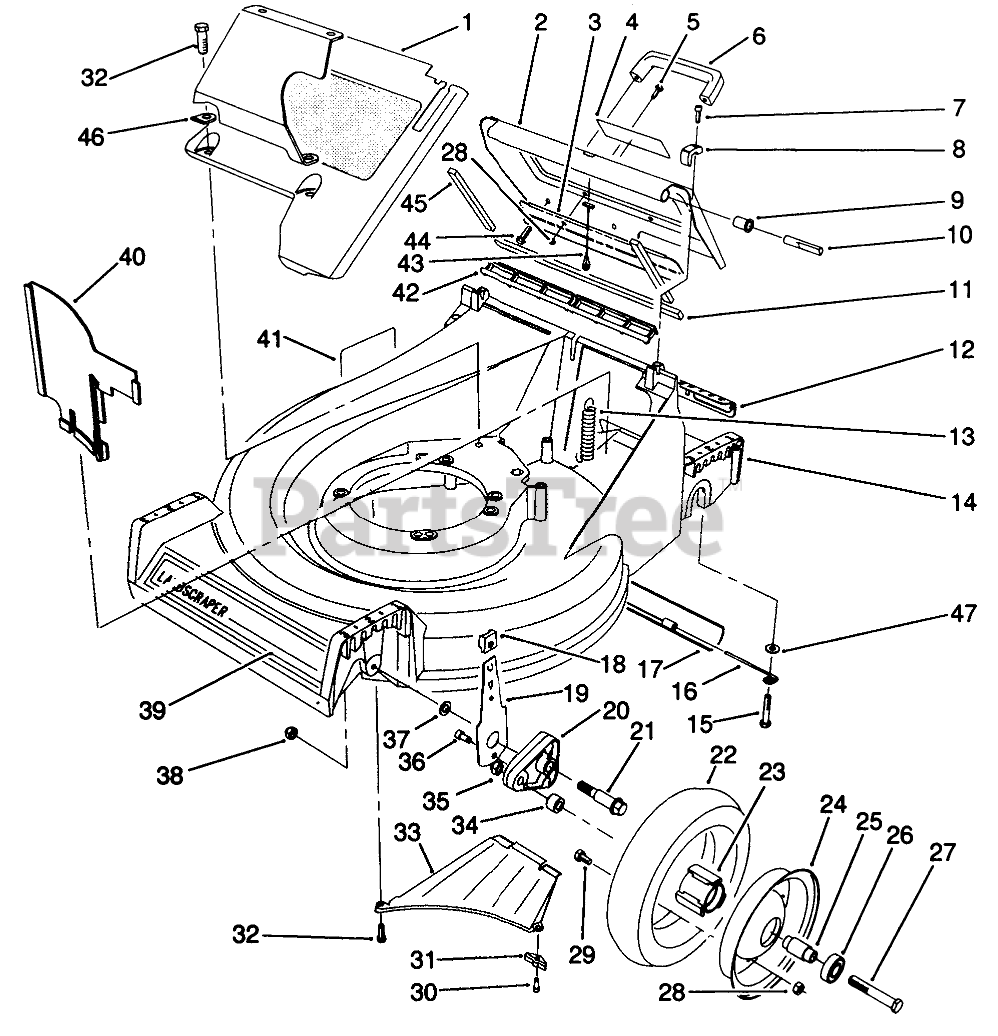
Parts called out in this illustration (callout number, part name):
1	PaneI-Screen
2	Door-Discharge
3	DOOR - BRACE
4	DECAL - WARNING
5	SCREW-HH
6	HANDLE-DOOR
7	SCREW-HSH
8	HINGE CLAMP
9	DOOR BUSHING
10	HINGE PIN
11	DOOR END SEAL
12	ACCESS COVER
13	EXTENSION-SPRING
14	HOUSING W/DECAL (R&S)
15	SCREW-SHOULDER
16	SHIELD HANGER
17	TRAILING SHIELD
18	KNOB-ARM
19	FRONT SPRING ARM ASM
20	ARM-PIVOT, FRONT
21	BOLT-SHOULDER
23	HUB-BEARING
24	Wheel-Half
25	SPACER-BEARING
26	BEARING-WHEEL
27	SCREW-HH
28	NUT-LOCK, NI
29	SCREW-HH
30	SCREW-HWHTF
31	Bracket-Discharge
32	SCREW-HWHTF
33	Ramp Discharge
34	SPACER-WHEEL
35	NUT-LOCK, NI
36	SCREW-HSH, THREAD FORMING
37	WASHER
38	Nut
39	DECAL - LANDSCAPER
40	PANEL-VERTICAL
41	DECAL-DANGER
42	DOOR SEAL
43	DOOR CABLE
44	SCREW-HWH
45	DOOR SIDE SEAL
46	BASE TANK
47	WASHER-FLAT
